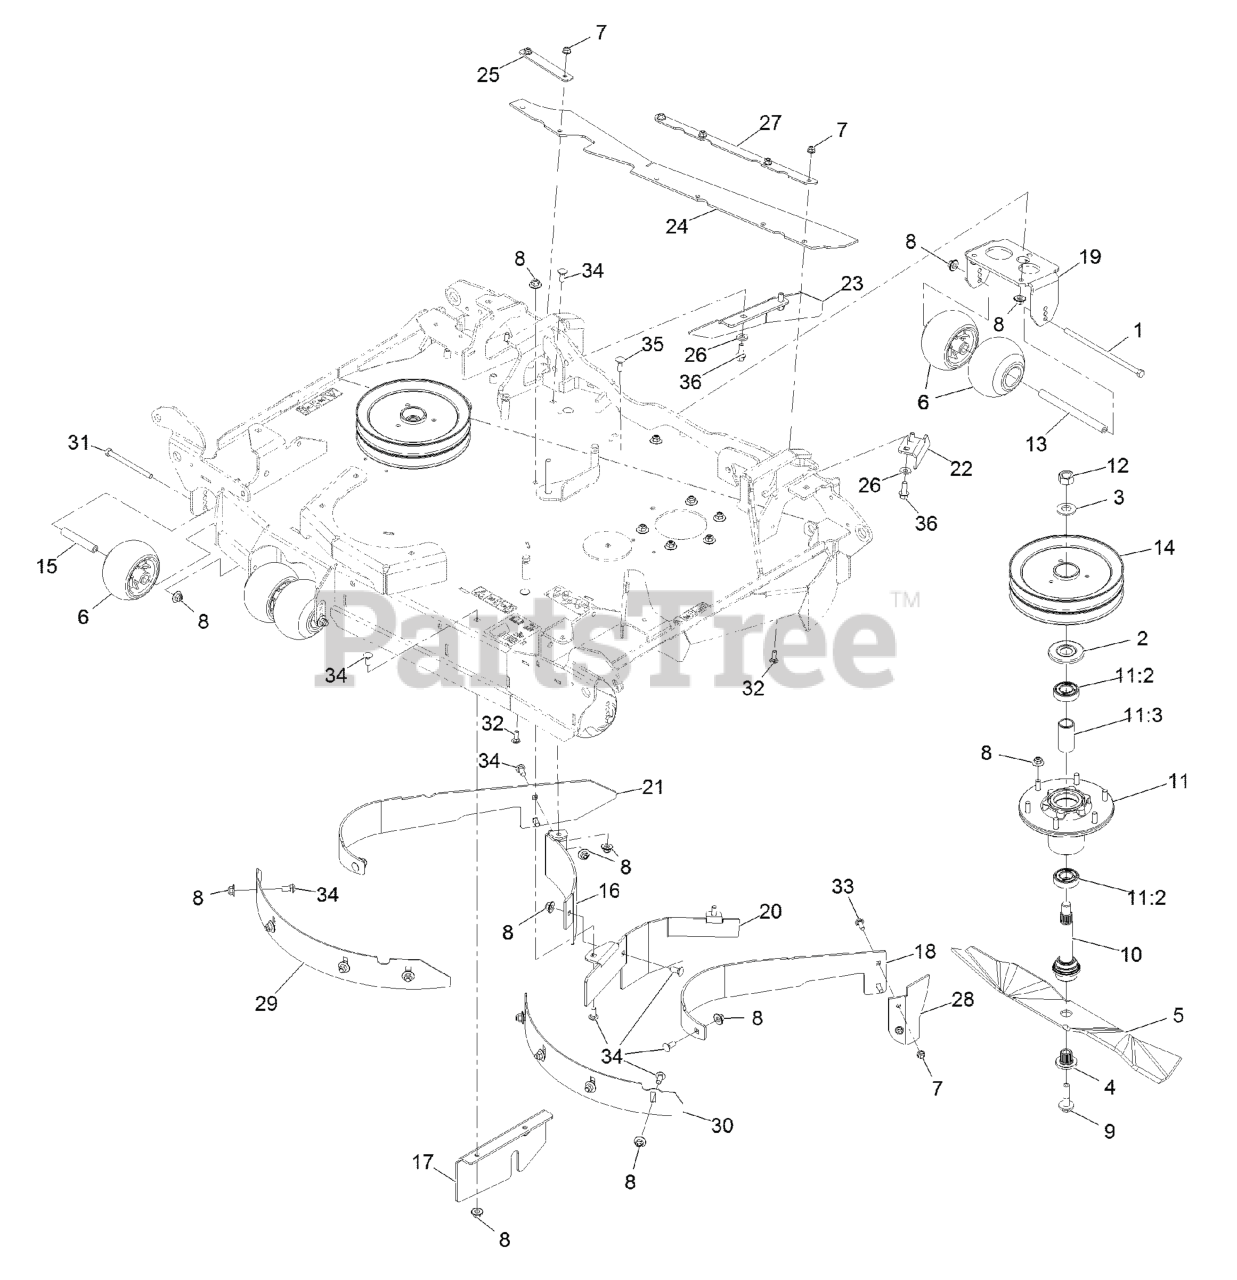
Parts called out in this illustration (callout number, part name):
1	SCREW-HH
2	GUARD-BEARING, TOP
4	BUSHING,SPLINED
6	ROLLER-SCALP, ANTI
7	NUT-HF, NI
8	Nut-Nyloc 3/8-16 Flg
9	SCREW,SEMS 1/2-20 X 2.19
10	ASM-SPINDLE AND SEAL
11	ASM-CUTTER HSG
11:2	BEARING-3205 TRASHGUARD
11:3	SPACER-BEARING
12	NUT-HEX
13	SPACER-WHEEL
14	SHEAVE-DOUBLE 96RD
15	SPACER-WHEEL SHORT
16	BAFFLE-CENTER, REAR (RH)
17	PLATE-BLOCK, FRONT
18	BAFFLE-DOGLEG, CENTER (LH
19	BRACKET-ANTISCALP, REAR
20	BAFFLE-CENTER
21	BAFFLE-DOGLEG, CENTER (RH
22	BAFFLE-BREAKER
23	PLATE-FIN, DISCHARGE
24	FLAP-DISCHARGE
25	SUPPORT-FLAP, LH
26	WASHER-BELLEVILLE
27	SUPPORT-FLAP, LH
28	GUARD-DISCHARGE
29	BAFFLE-DEPTH, LH
30	BAFFLE-DEPTH, RH
31	SCREW-HH
32	SCREW-CARR
33	SCREW-CARR
34	BOLT-CARR
35	BOLT-CARR
36	SCREW-HHF
